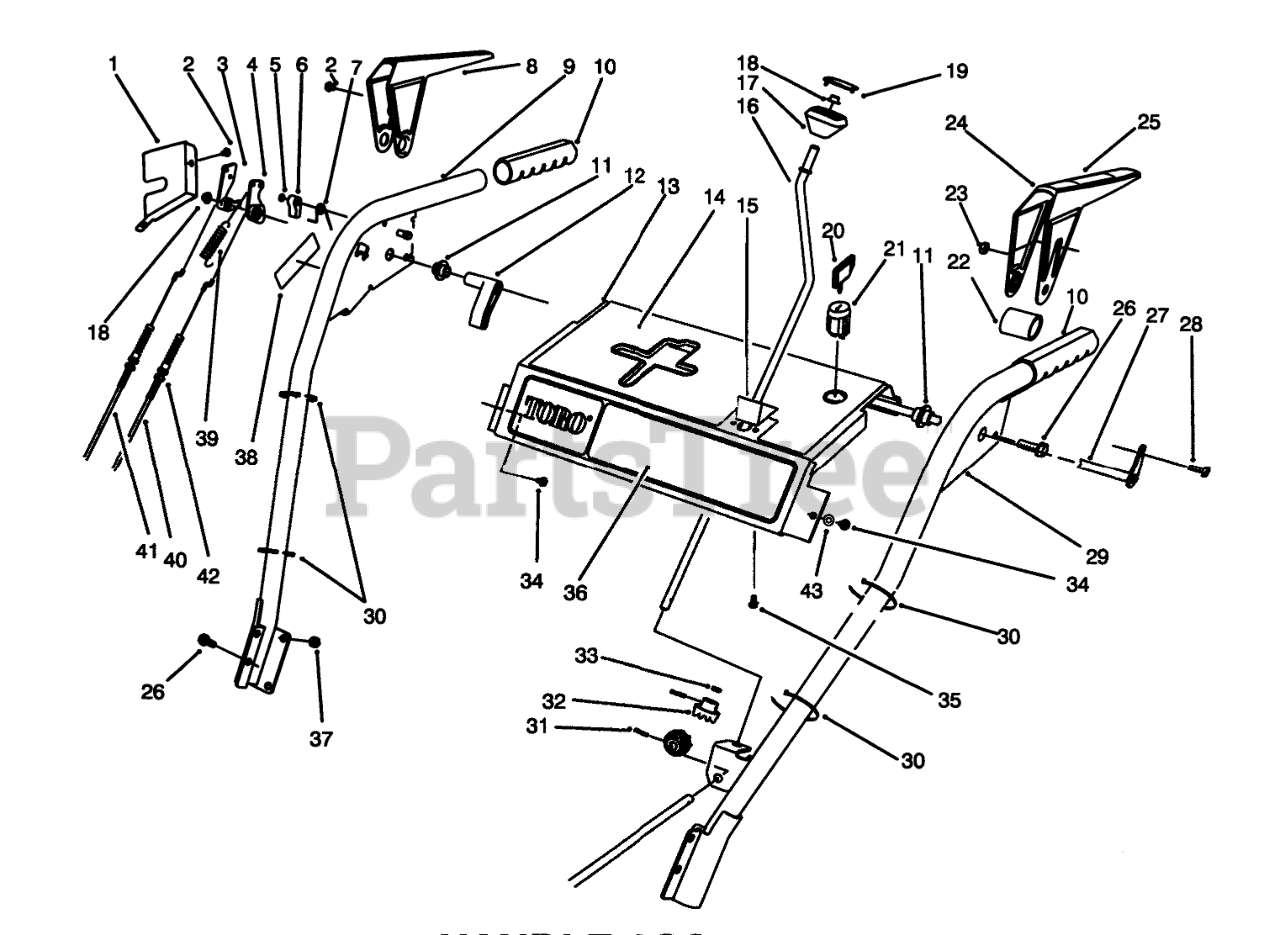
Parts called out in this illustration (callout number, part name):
1	Cover Lever Lock
2	SCREW-HH
3	TANG-LOCKING
4	CAM-RELEASE
5	E-RING-RETAINER
6	LATCH-LOCKING
7	SPRING-TORSION
8	Lever-Impeller
9	Handle-R.H.
10	GRIP-HANDLE
11	BUSHING-LEVER
12	LEVER-TRIP
13	Panel-Control
14	DECAL-TOP PANEL
15	PLATE-GUIDE
16	CRANK-ROD, CHUTE
17	KNOB-CONTROL, CHUTE
18	RETAINER-PUSH ON
19	COVER-KNOB
20	KEY-IGNITION
21	SWITCH
22	SPACER-LEVER, TRACTION
23	NUT-LOCK, NI
24	Lever-Traction
25	DECAL-LEVER
26	SCREW-HHF
27	CROSS ROD ASM
28	SCREW-HWH
29	Handle-L.H.
30	TIE-CABLE
31	PIN-SPRING
32	GEAR-UNIVERSAL
33	WASHER-RUBBER
34	SCREW-HWHTF
35	SCREW-PPH
36	DECAL-FRT PANEL (1132)
37	NUT-LOCK, NI
38	DECAL-WARNING
39	SPRING-EXTENSION
40	CABLE-TRACTION
41	CABLE-IMPELLER
42	NUT-LOCK, NI
43	WASHER-FLAT
